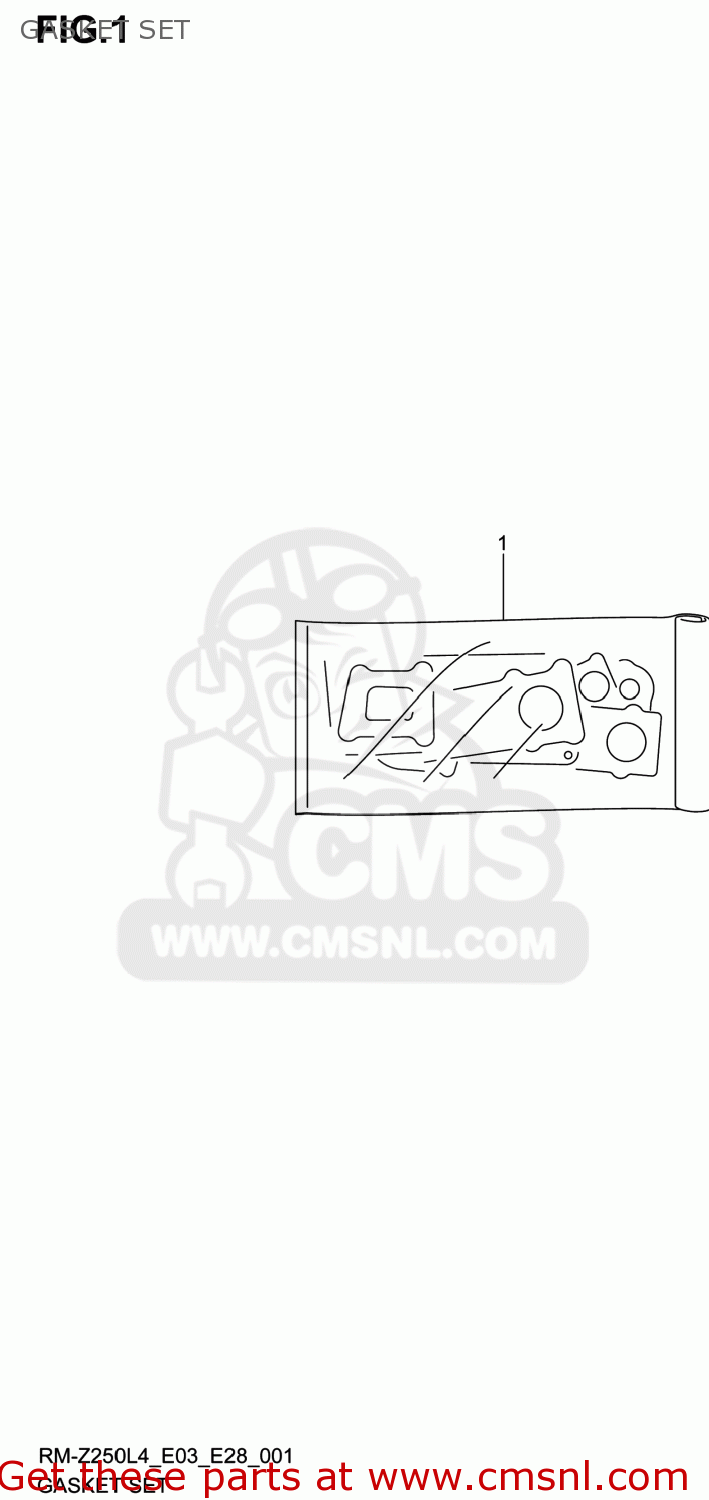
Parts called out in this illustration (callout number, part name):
1	GASKET SET (NAS)
2	GASKET,CYLINDER HEAD (NAS)
3	GASKET,CYL HEAD COVER NO.1 (NAS)
4	GASKET,CYL HEAD COVER NO.2 (NAS)
5	WASHER,CYL HEAD COVER
6	GASKET,CYLINDER (NAS)
7	GASKET,CRANKCASE (NAS)
8	GASKET,CLUTCH COVER (NAS)
9	GASKET,MAGNETO COVER (NAS)
10	GASKET,CLUTCH COVER OUTER (NAS)
11	GASKET,EXHAUST PIPE (NAS)
12	O RING,WATER PUMP CASE
13	O RING(D:1.9,ID:18.8)
